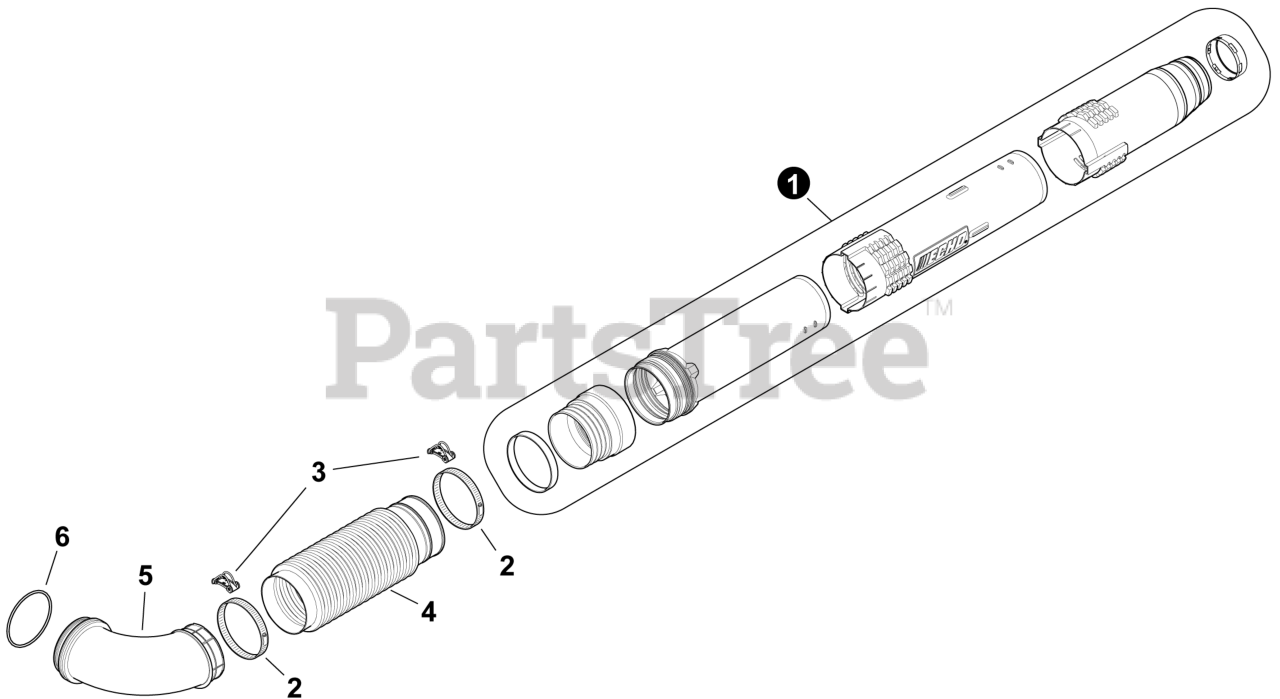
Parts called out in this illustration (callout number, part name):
1	BLOWER TUBE ASSEMBLY
2	CLAMP, BLOWER TUBE
3	CLIP, CABLE
4	TUBE, FLEXIBLE BLOWER
4	TUBE, BLOWER - FLEXIBLE
5	TUBE, BLOWER - ELBOW
5	TUBE, ELBOW BLOWER
